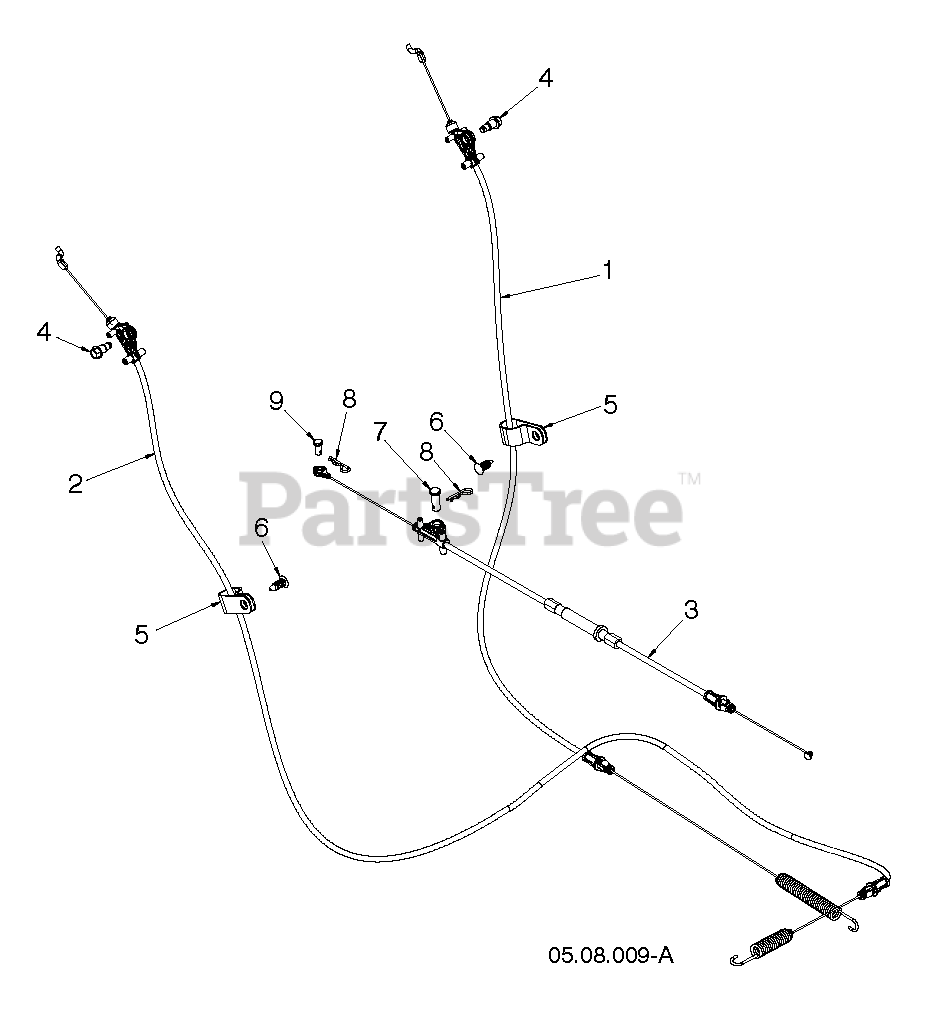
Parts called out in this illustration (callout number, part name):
1	Drive Control Cable, DSST OPP
2	Auger Control Cable, DSST High-Crank
3	Speed Control Cable, DSST OPP
4	Shoulder Bolt, 1/4-20 Trilob
5	CLIP.CABLE.BLK
6	FASTENER.PUSH.O.250X0.783
7	Clevis Pin, 5/16 X .875
9	Clevis Pin, .25 X .31
